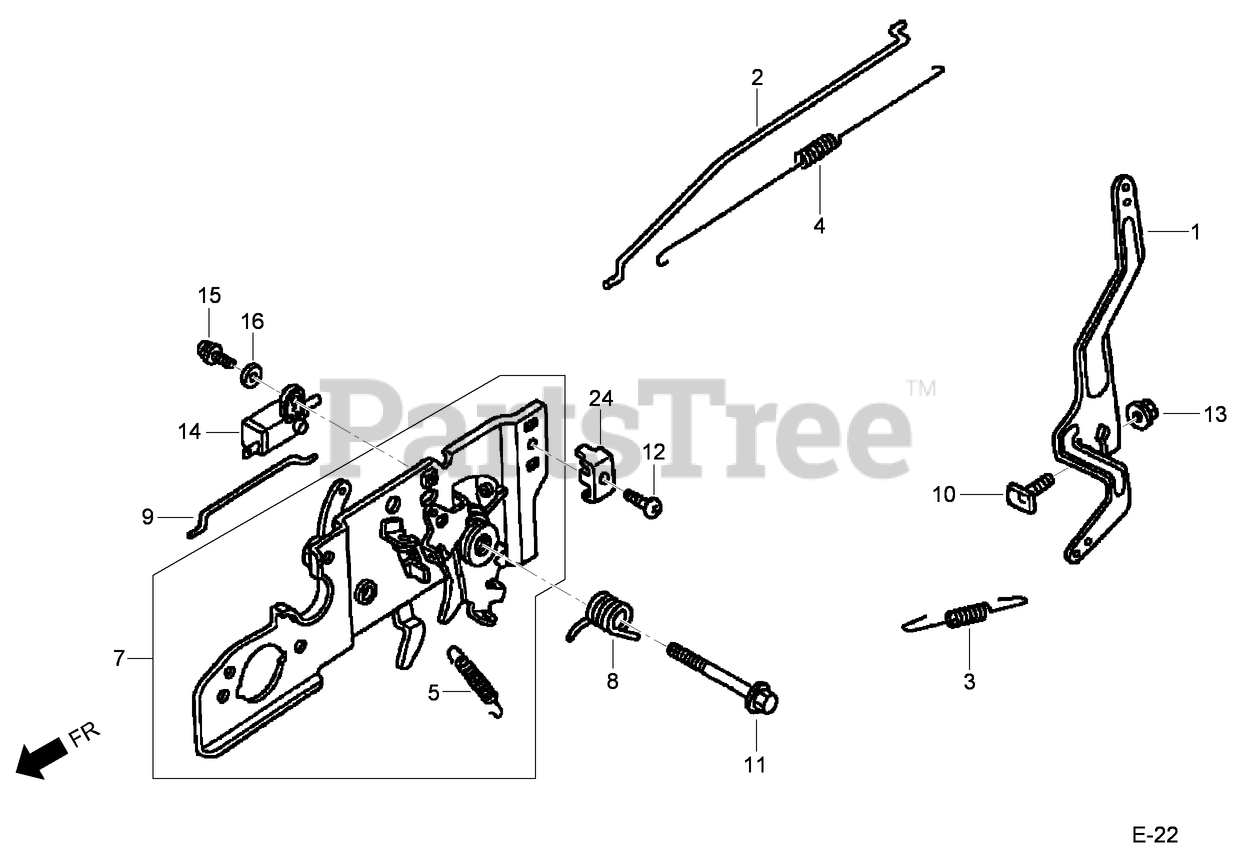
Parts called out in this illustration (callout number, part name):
1	ARM-GOVERNOR
2	ROD-GOVERNOR (engine serial numbers up to 6349022)
2	ROD-GOVERNOR (engine serial numbers starting at 6349023)
3	SPRING-GOVERNOR
4	SPRING-RETURN, THROTTLE
5	Spring-Lever
7	BASE-CONTROL
8	SPRING-RETURN, CONTROL LEVER
9	ROD-CHOKE
10	BOLT-ARM, GOVERNOR
11	BOLT-FLANGE (6X45) (CT200)
12	Screw-Pan (5X16)
13	NUT-FLANGE (6 mm)
14	ENGINE STOP SWITCH ASM
15	SCREW-WASHER (4X12)
16	WASHER-PLAIN (4MM)
24	HOLDER-CABLE
